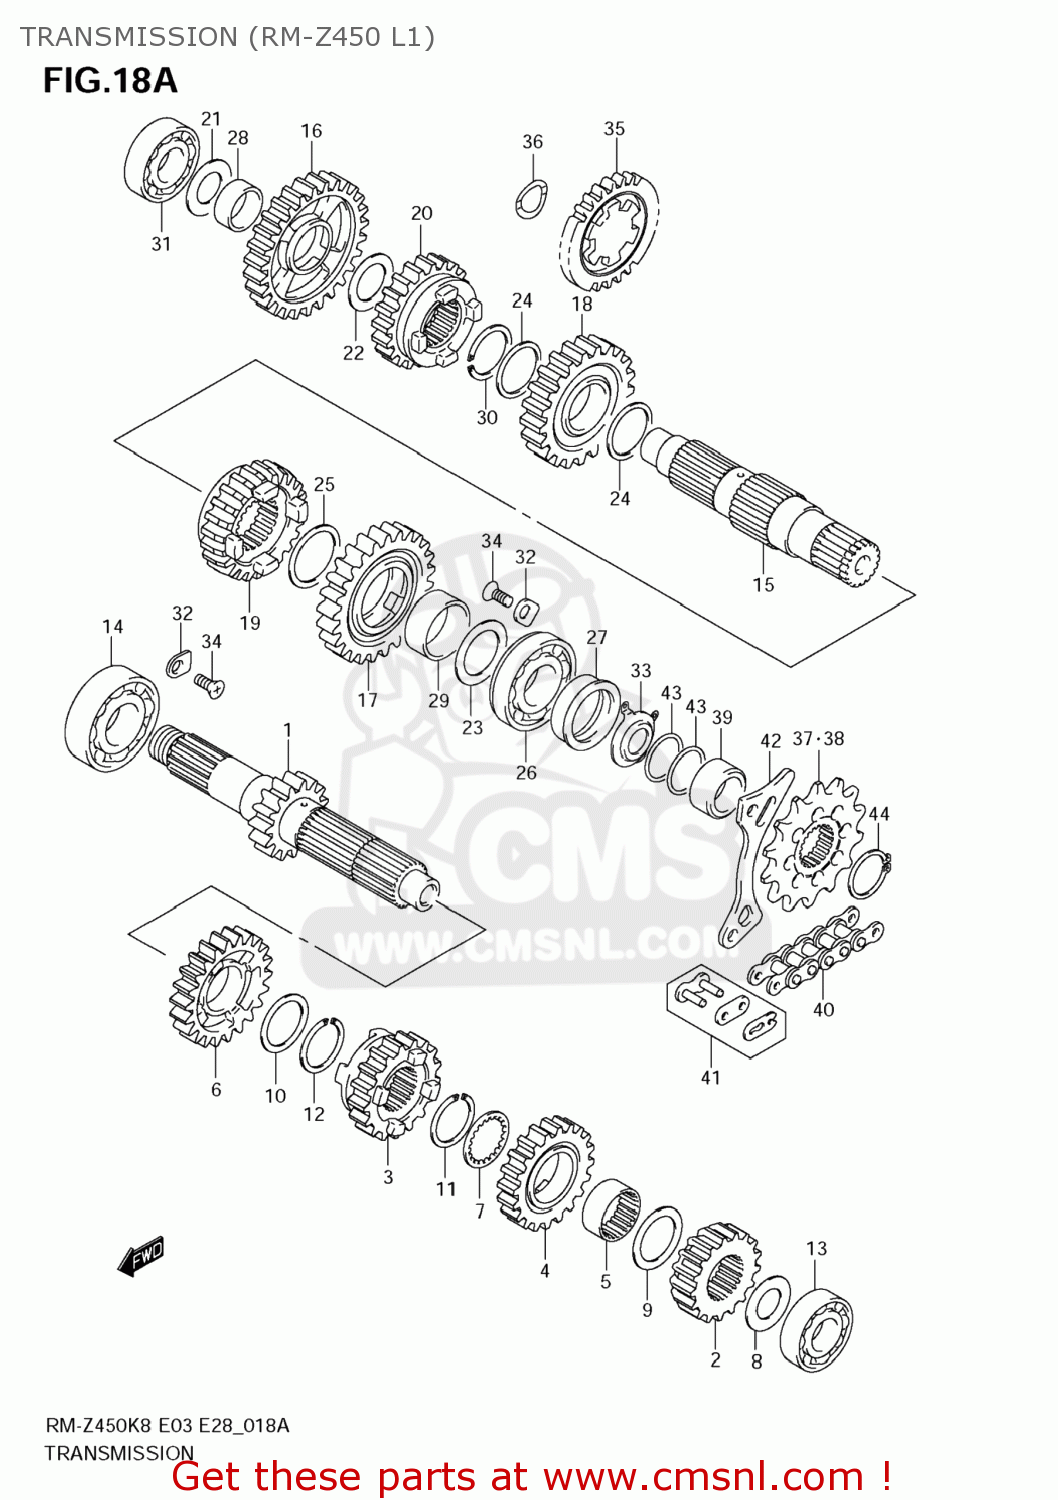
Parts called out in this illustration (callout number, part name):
1	SHAFT,COUNTER
2	GEAR,2ND DRIVE
3	GEAR,3RD DRIVE
4	GEAR,4TH DRIVE
5	BUSH,4TH DRIVE GEAR
6	GEAR,5TH DRIVE
7	WASHER,LOCK
8	SHIM(17X30X1)
9	SHIM(25X34X1)
10	SHIM(25X32X1)
11	CIRCLIP
12	CIRCLIP
13	BEARING
14	BEARING
15	SHAFT,DRIVE
16	GEAR,1ST DRIVEN
17	GEAR,2ND DRIVEN
18	GEAR,3RD DRIVEN
19	GEAR,4TH DRIVEN
20	GEAR,5TH DRIVEN
21	SHIM(17X30X1)
22	SHIM(20X30X1)
23	SHIM(24X34X1)
24	SHIM(25X30X1)
25	SHIM(27X33X1)
26	BEARING(24X56X14)
27	SEAL,OIL(31X40X6.7)
28	BUSH(20X24X10)
29	BUSH(27X31X13)
30	CIRCLIP
31	BEARING
32	RETAINER,COUNTER BEARING,R
33	RETAINER,DRIVE SHAFT OIL SEAL
34	SCREW(6X12)
35	GEAR,KICK STARTER IDLE
36	WASHER,KICK IDLE
37	SPROCKET,ENGINE(NT:13)
38	SPROCKET,ENGINE(NT:14)
39	SPACER,ENGINE SPROCKET
40	CHAIN,DRIVE
41	JOINT SET,CHAIN
42	PLATE,FR CHAIN GUIDE
43	O RING(D:1.9,ID:21.8)
44	CIRCLIP
